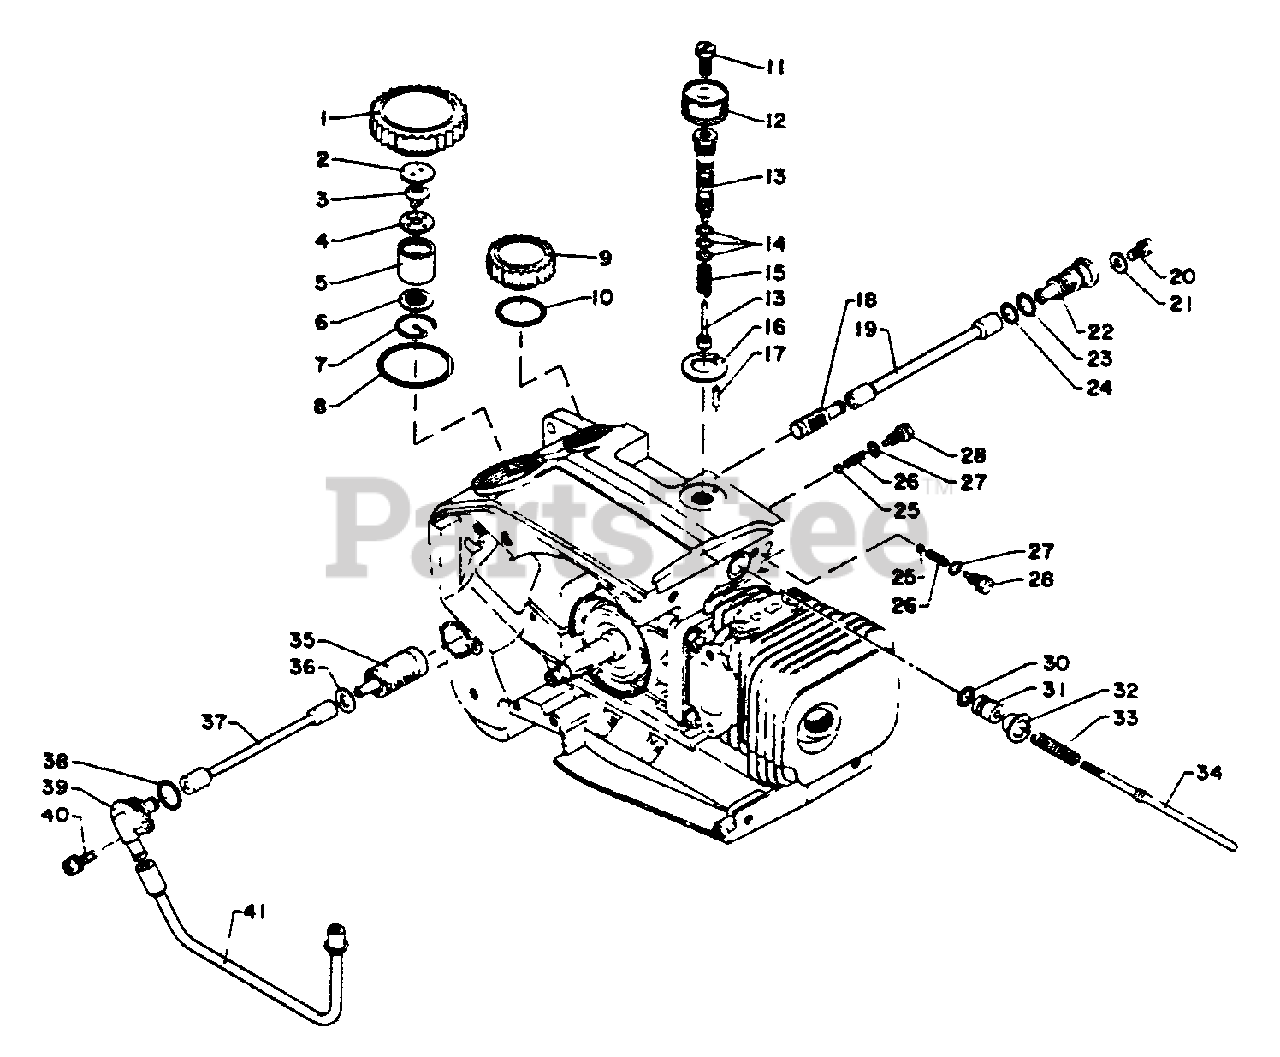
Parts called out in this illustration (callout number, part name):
1	CAP ASSY
3	VALVE, CHECK
4	HOLDER, VENT
6	FILTER, FUEL
7	RING, RETAINING
8	O-RING 29
9	CAP ASSY
10	O-RING 16 MM
11	SCREW 5×14
12	DIAL, AUTO-OILER
13	PUMP KIT
16	FLAT SPRING
17	BEARING, NEEDLE
18	FILTER, OIL
19	PIPE
20	SCREW 4×10
21	WASHER
22	CONNECTOR, PIPE
23	O-RING 9 MM
24	O-RING 8 MM
25	VALVE, BALL
26	SPRING, VALVE
28	ADAPTOR, OIL PUMP
30	O-RING 6 MM
31	PUMP PISTON
32	RETAINER, SPRING
33	SPRING, OIL PUMP
34	PUMP ROD
35	FILTER, FUEL
36	WASHER 6.5×11.5×0.8
37	PIPE - INNER
38	O-RING 12 MM
39	CONNECTOR, PIPE
40	SCREW 4×14
41	PIPE, FUEL - OUTER
